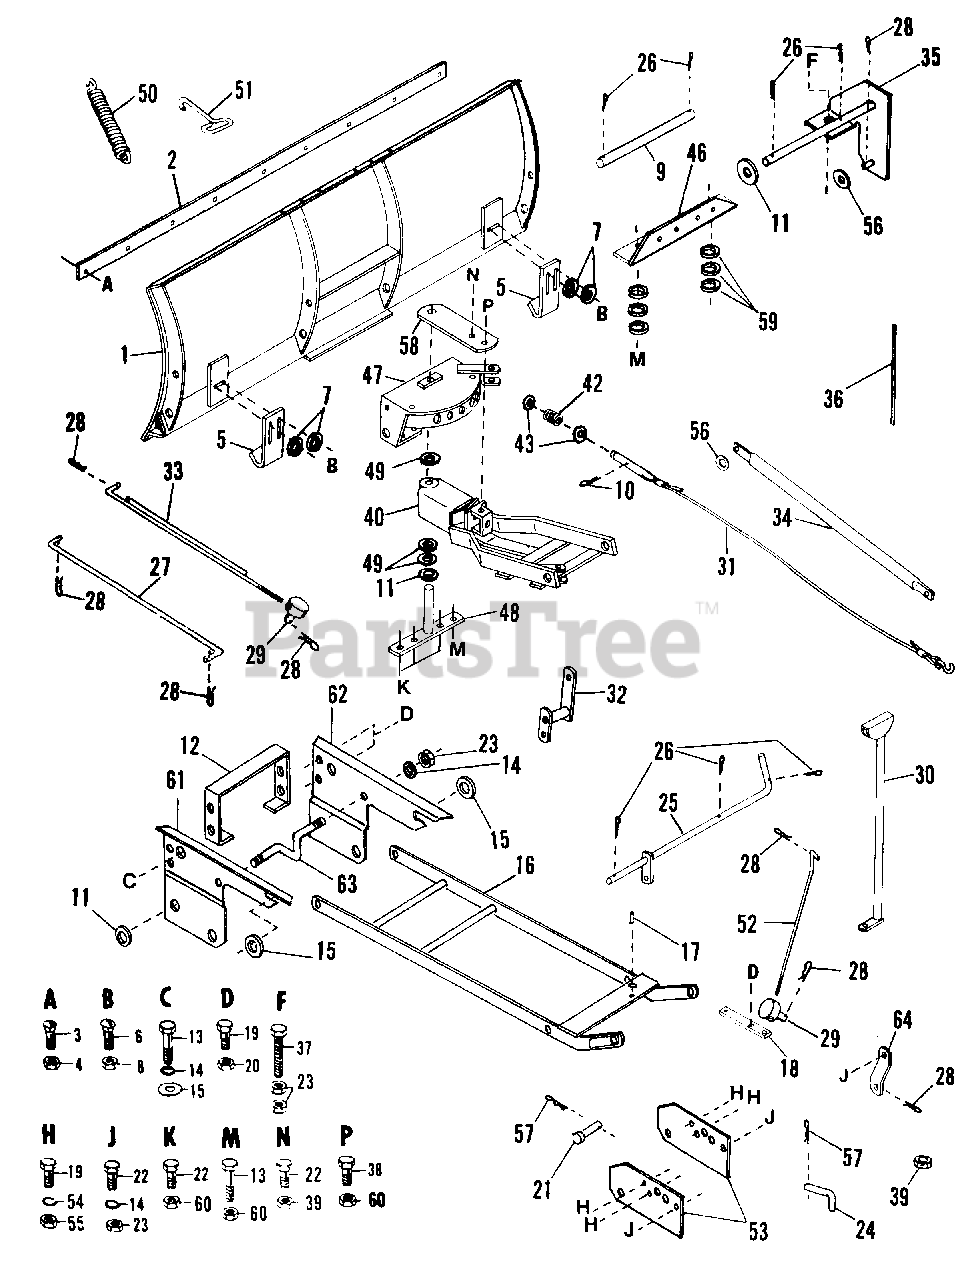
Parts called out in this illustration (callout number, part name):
1	Blade Assembly
2	Cutting Edge Blade
3	Bolt-5/16-18 x 1" Carriage
4	Nut & Lock Washer Assembly-5/16-18
5	Skid Shoe
6	Bolt-3/8-16 x 1 1/4 Carriage
7	Washer - 7/16" x 1" x .083 Flat
8	Nut 4 Lock Washer Assembly-3/8-16 Hex
9	Locating Pin
10	Cotter Pin
11	Washer-13/16" x 1-1/2" x .134 Flat
12	Front Mounting Frame Assembly
13	Bolt - 1/2-13 x 1-1/2" Hex Head
14	Washer -1/2" Med Lock
15	Washer - 1/2" x 1-1/4" x .083 Flat
16	Mounting Frame Assembly
17	Roll Pin
18	Pivot Control Strap
19	Bolt - 3/8-16 x 1" Hex Head
20	Nut - 3/8-16 Hex Lock
21	Clevis Pin
22	Bolt - 1/2-13 x 1-1/4" Hex Head
23	Nut - 1/2-13 Light Hex
24	Locating Pin
25	Pivot Arm Assembly
26	Cotter Pin - 3/16" x 1-3/4"
27	Pivot Rod
28	Hair Cotter Pin
30	Pivot Control Handle Assembly
31	Pivot Control Cable & Lock Pin Assembly
32	Bell Crank Assembly
33	Pivot Control Rod Assembly
34	Lift Tube
35	Lift Are Assembly
36	Plastic Cable
37	Bolt - 1/2-13 x 2" Full Thread
38	Bolt - 1/2-13 x 1" Hex Head
39	Nut - 1/2-13 Half Hex
40	"A" Frame Assy
43	Washer - 21/32" x 1-5/16" x .095 Flat
46	Pivot Stop Angle
47	Pivot Box Assembly
48	Pivot Pin Assembly
50	Breakover Spring
51	Spring Mounting Hook
52	Pivot Control Rod
53	Anchor Plate
54	Washer - 3/8" Medium Lock
55	Nut - 3/8-16 Light Hex
56	Washer - 17/32" x 1-1/16" x .095 Flat
57	Hair Cotter Pin
60	Nut - 1/2-13 Hex Lock
61	Side Mounting Plate LH
62	Side Mounting Plate RH
63	Front Mounting Frame Rod
64	Cross Shaft Support Strap
